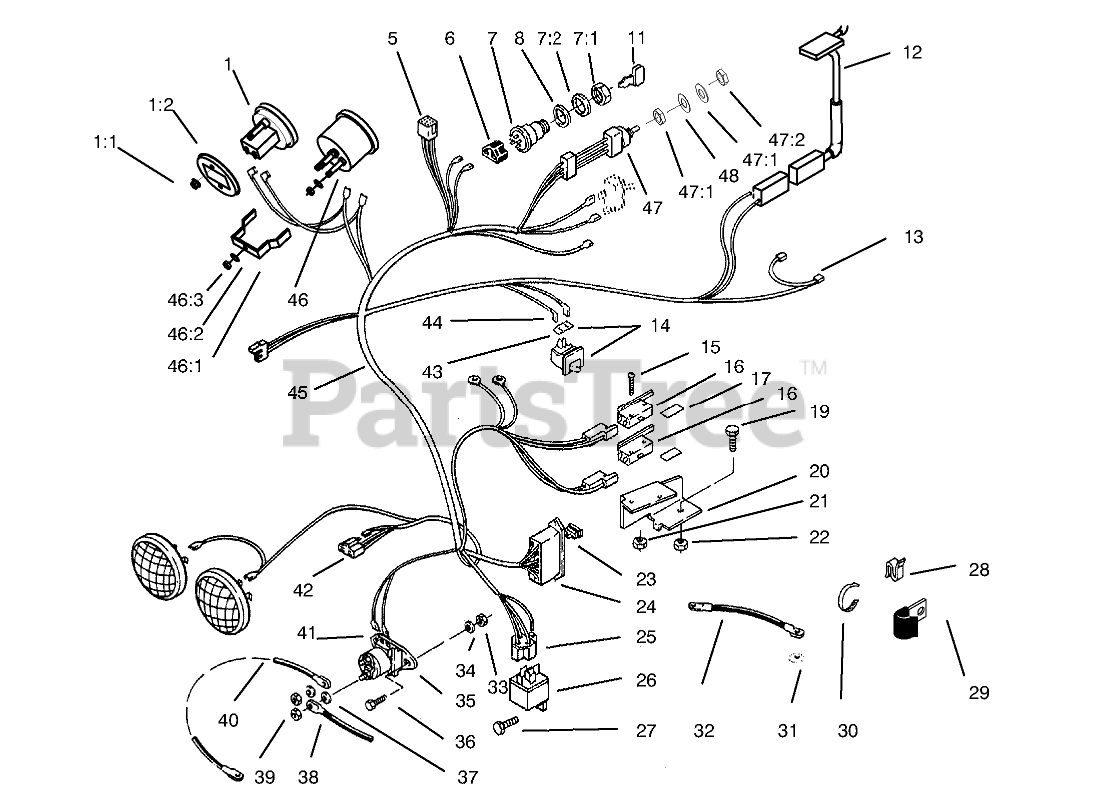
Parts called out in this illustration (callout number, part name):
1	Hourmeter
1:1	NUT-HEX, KEPS
1:2	Retainer
5	Terminal
6	CONNECTOR BODY ELECT
7	KEY SWITCH ASM
7:2	Washer-Lock
8	WASHER
11	KEY-IGNITION
12	SWITCH-SEAT
13	Sur-Plug
14	Switch-Interlock, (Incl. Ref. #43)
15	Screw
16	SWITCH
17	BARRIER - SWITCH
19	Bolt
20	BRACKET-SWITCH
21	NUT HEX 4-40 ELAST
23	FUSE-BLADE, 15 AMP
24	FUSE-HOLDER 4 WAY
25	TERMINAL 10
26	RELAY
27	Screw
28	CLIP-CABLE
29	CLIP
30	TIE-CABLE
31	WASHER-LOCK, INTERNAL
32	WIRE GROUND
33	NUT-HEX
34	Washer-Lock
35	Solenoid
38	CABLE-BLACK
39	NUT-JAM
40	ASSY WIRE
41	TERMINAL 10
42	5-CONTACT CONN BODY
43	SHIELD-DIRT SPST
44	Terminal
45	Wire Harness (Incl. Ref.# 5,6,13,24,25,42&45)
46	VOLTMETER
46:1	CLAMP-MOUNTING
46:2	WASHER-LOCK / EXT
46:3	NUT-HEX
47	SWITCH-LIGHTS
47:1	WASHER-LOCK
48	WASHER
